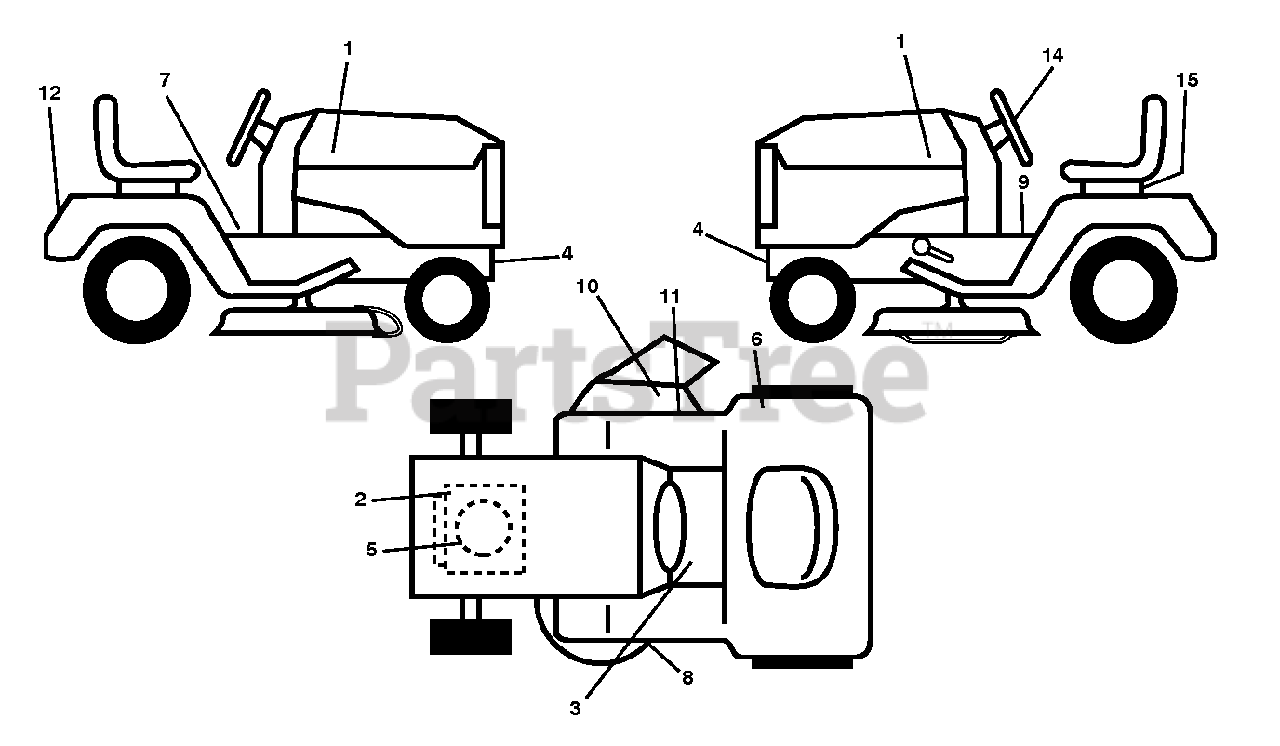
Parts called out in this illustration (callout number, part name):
6	Decal, 100 DB/CE
8	DECAL.V-BELT.SCHEMATIC.36/38/9
9	DECAL PARK BRAKE
10	DECAL.INTERNATIONL.CUTFINGER
11	DECAL, DEFLECT WARNING
15	DECAL BTRY SYMBOLS
